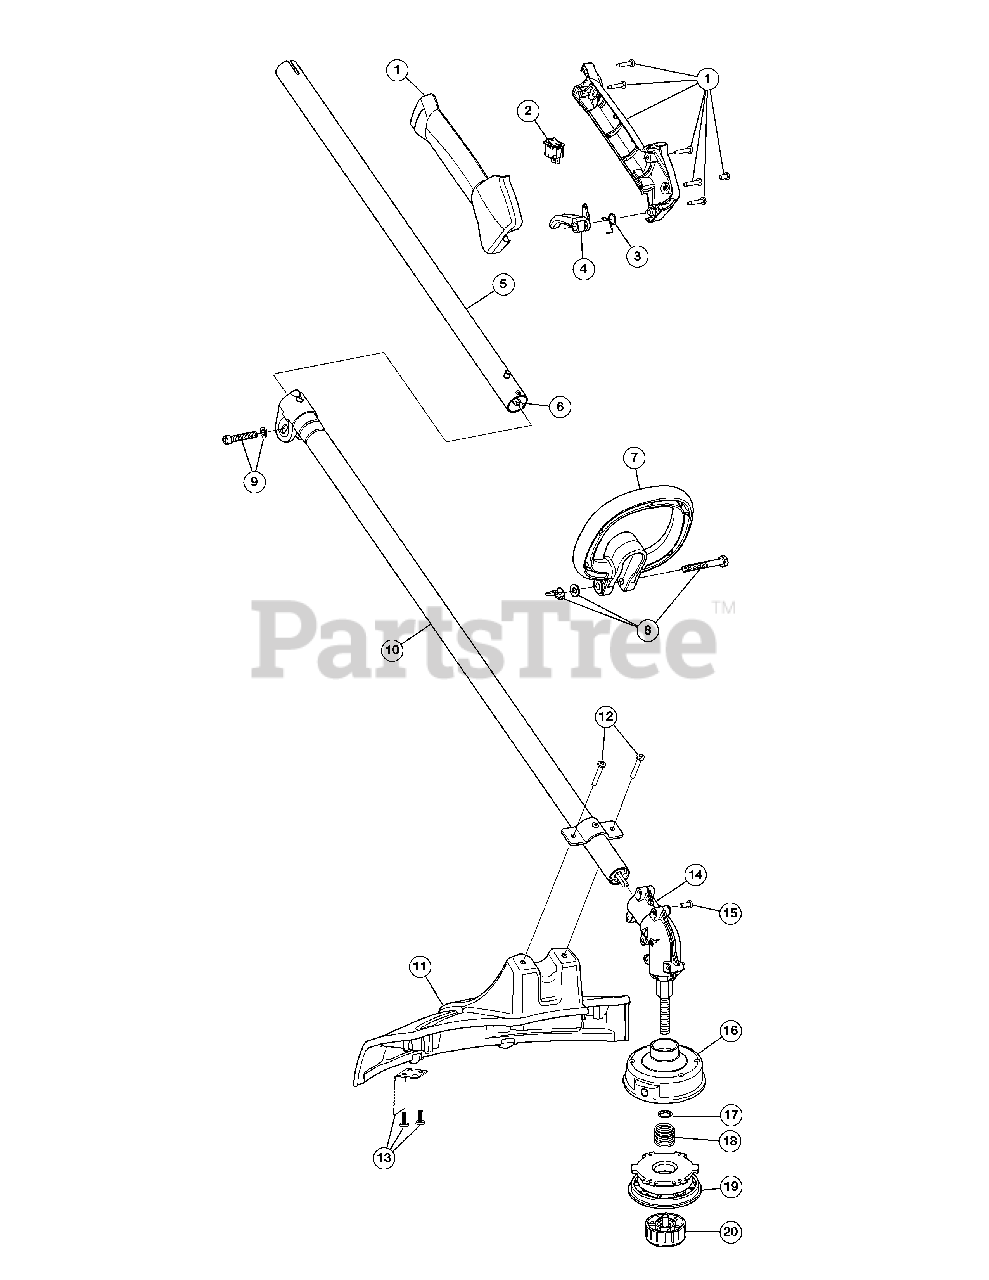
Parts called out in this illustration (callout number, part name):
1	Throttle Housing Assembly (Incl. 2 - 4)
2	Switch Assembly
3	Throttle Trigger Spring
4	Throttle Trigger
5	Upper Shaft Housing Assembly (Incl. 6)
6	Upper Flexible Drive Shaft
7	D-Handle (Incl. 8)
8	D-Handle Hardware Assembly
9	Clamp Hardware
10	Lower Shaft Housing Assembly
11	Shield Assembly (Incl. 12 & 13)
12	Shield Mounting Screw
13	Blade Assembly
14	Gearbox Assembly (Incl. 15 - 20)
15	Anti-Rotation Screw
16	Outer Spool Assembly (Incl. 17)
17	Retainer
19	Inner Reel
20	Bump Head Knob Assembly
